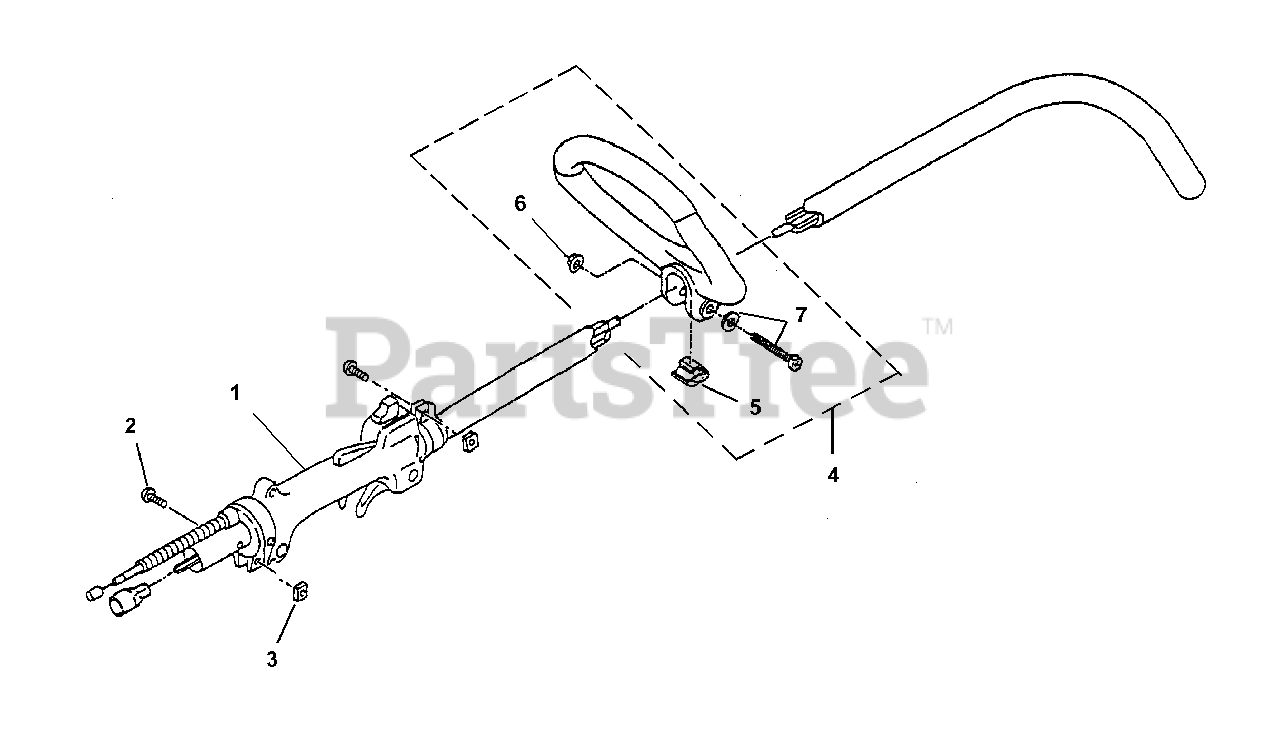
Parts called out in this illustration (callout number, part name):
1	CONTROL LEVER ASSEMBLY
4	HANDLE ASSEMBLY
6	NUT-Flange (M6)
7	BOLT-Cross Recess
